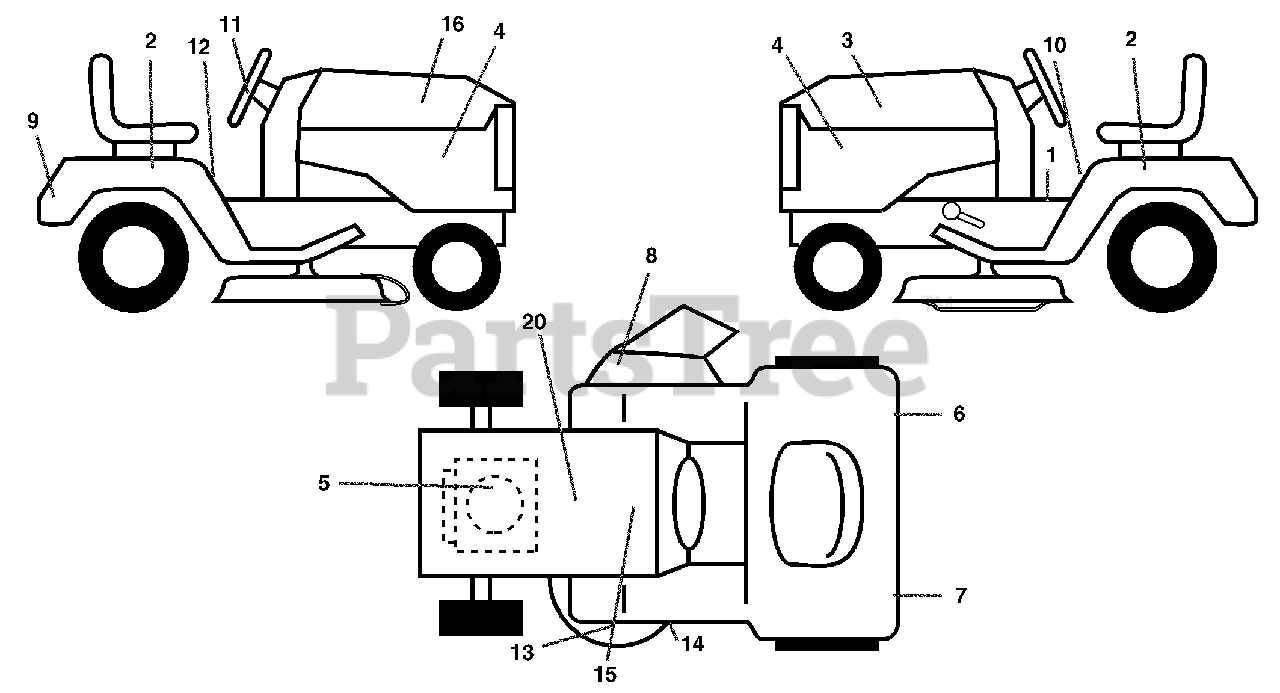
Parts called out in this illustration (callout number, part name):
1	Decal Dash
2	Decal Fender Auto
3	Decal Hood LH
4	Decal Side Panel
5	Decal HP Engine
6	Decal Reflector Rh
7	Decal Reflector Lh
9	Decal Fender Logo
10	Decal Fender Danger E/F
11	Decal Ins Strg Whl
12	Decal Fender Oper Cruise
13	Decal Deck Caution
14	Decal V-Belt Schematic
15	Decal Replace
16	Decal Hood Rh
20	Decal Bat Dan/Psn
